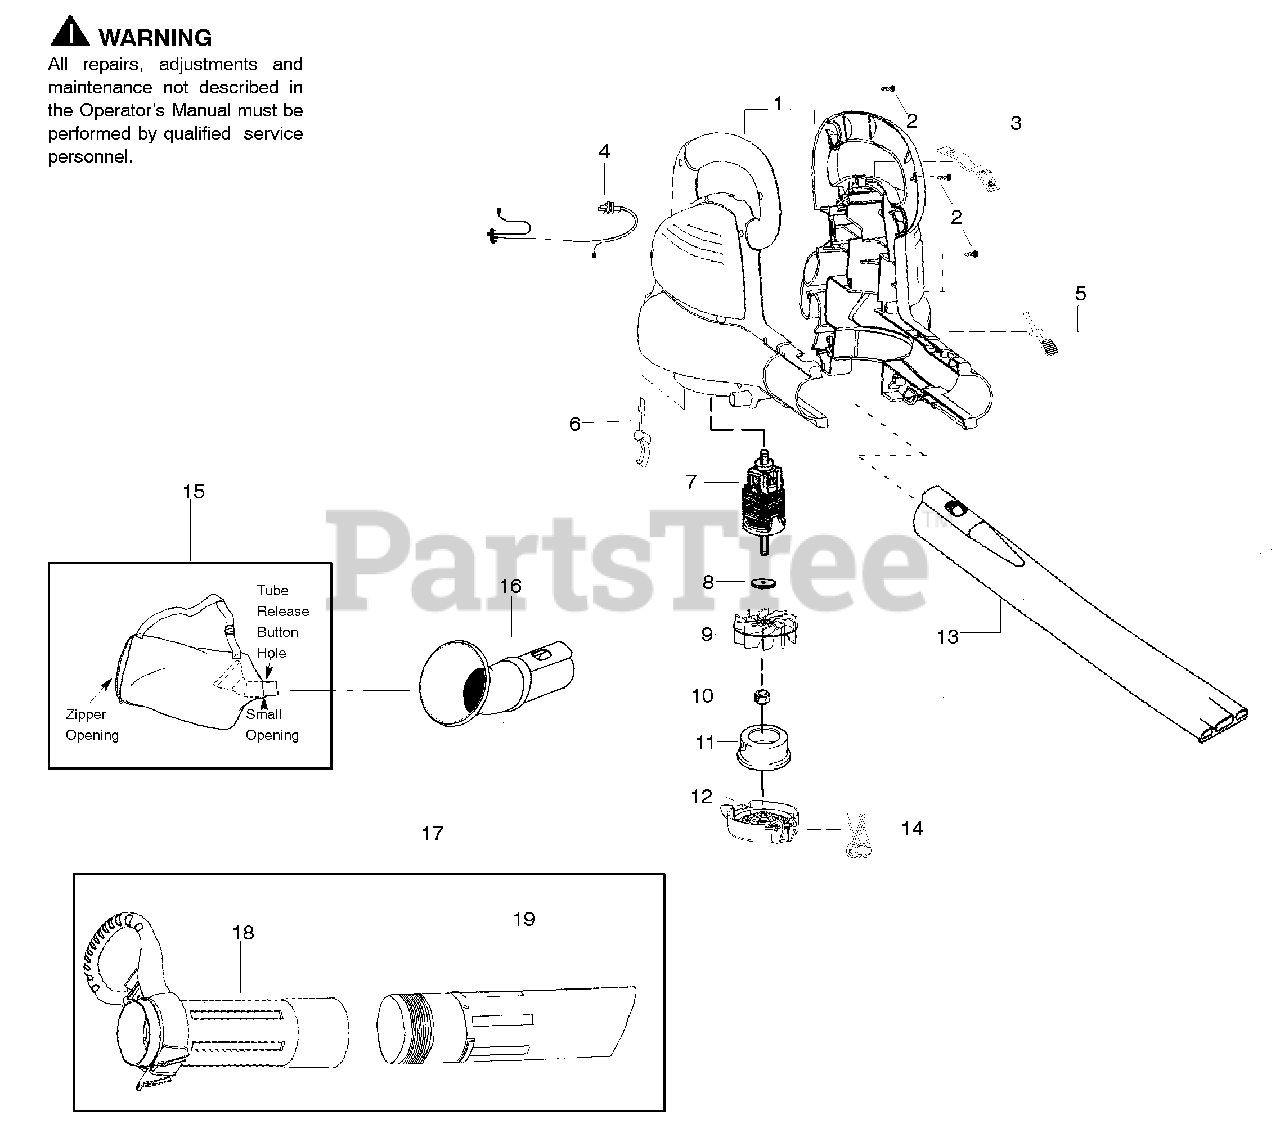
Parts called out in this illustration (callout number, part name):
1	Housing Set
3	Cover - Switch
4	Assy. Wiring Harness
5	Button - Tube Latch
6	Button - Door Latch
7	Assy. Motor
9	Impeller
10	Nut - Impeller
11	Restrictor - Inlet
12	Door - Vacuum Inlet
13	Tube - Blower
14	Spring - Door
15	Assy. - Vac Bag
16	Attachment-Vac Bag
17	Kit-Upper/Lower Tube w/handle
18	Tube - Upper Vac w/handle
19	Tube - Inlet Vacuum
